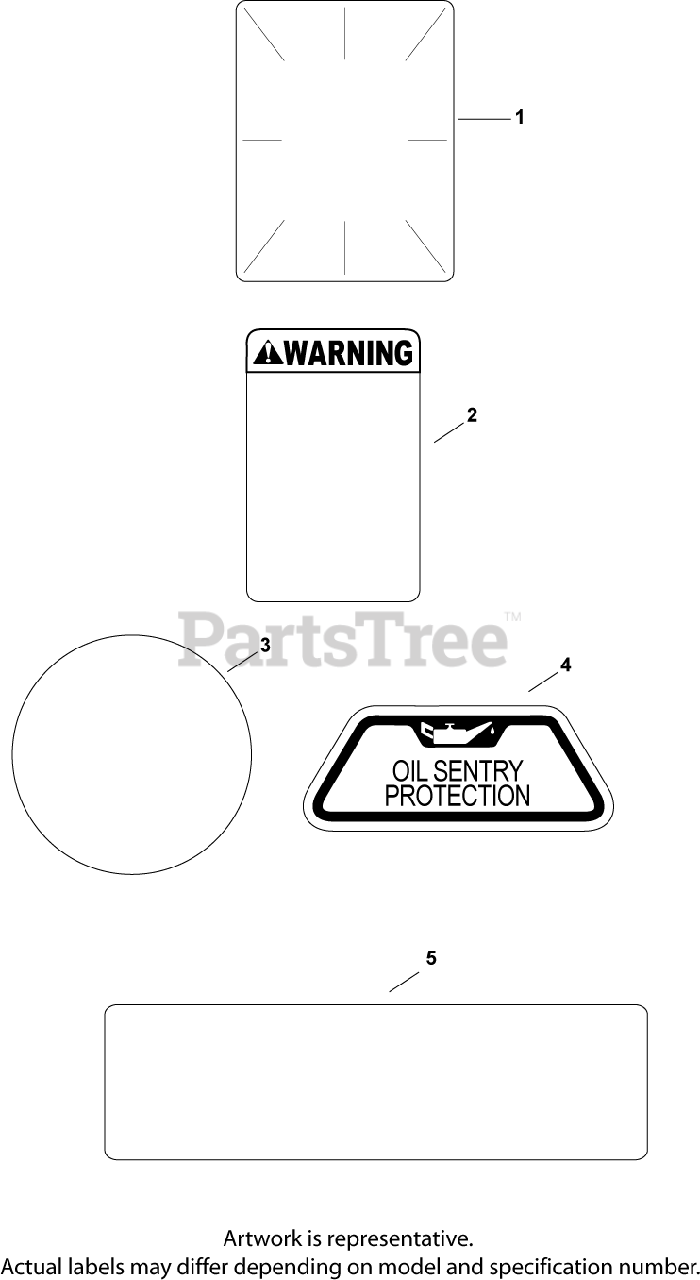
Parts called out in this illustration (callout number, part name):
1	DECAL, CLEAR LAMINATE USE 25 113 70-S
2	DECAL, CO WARNING
3	DECAL, GRASS SCREEN USE 24 113 499-S
4	DECAL, OIL SENTRY - (#DSC)
5	DECAL, COMMAND (GASEOUS) - DISCONTINUED
